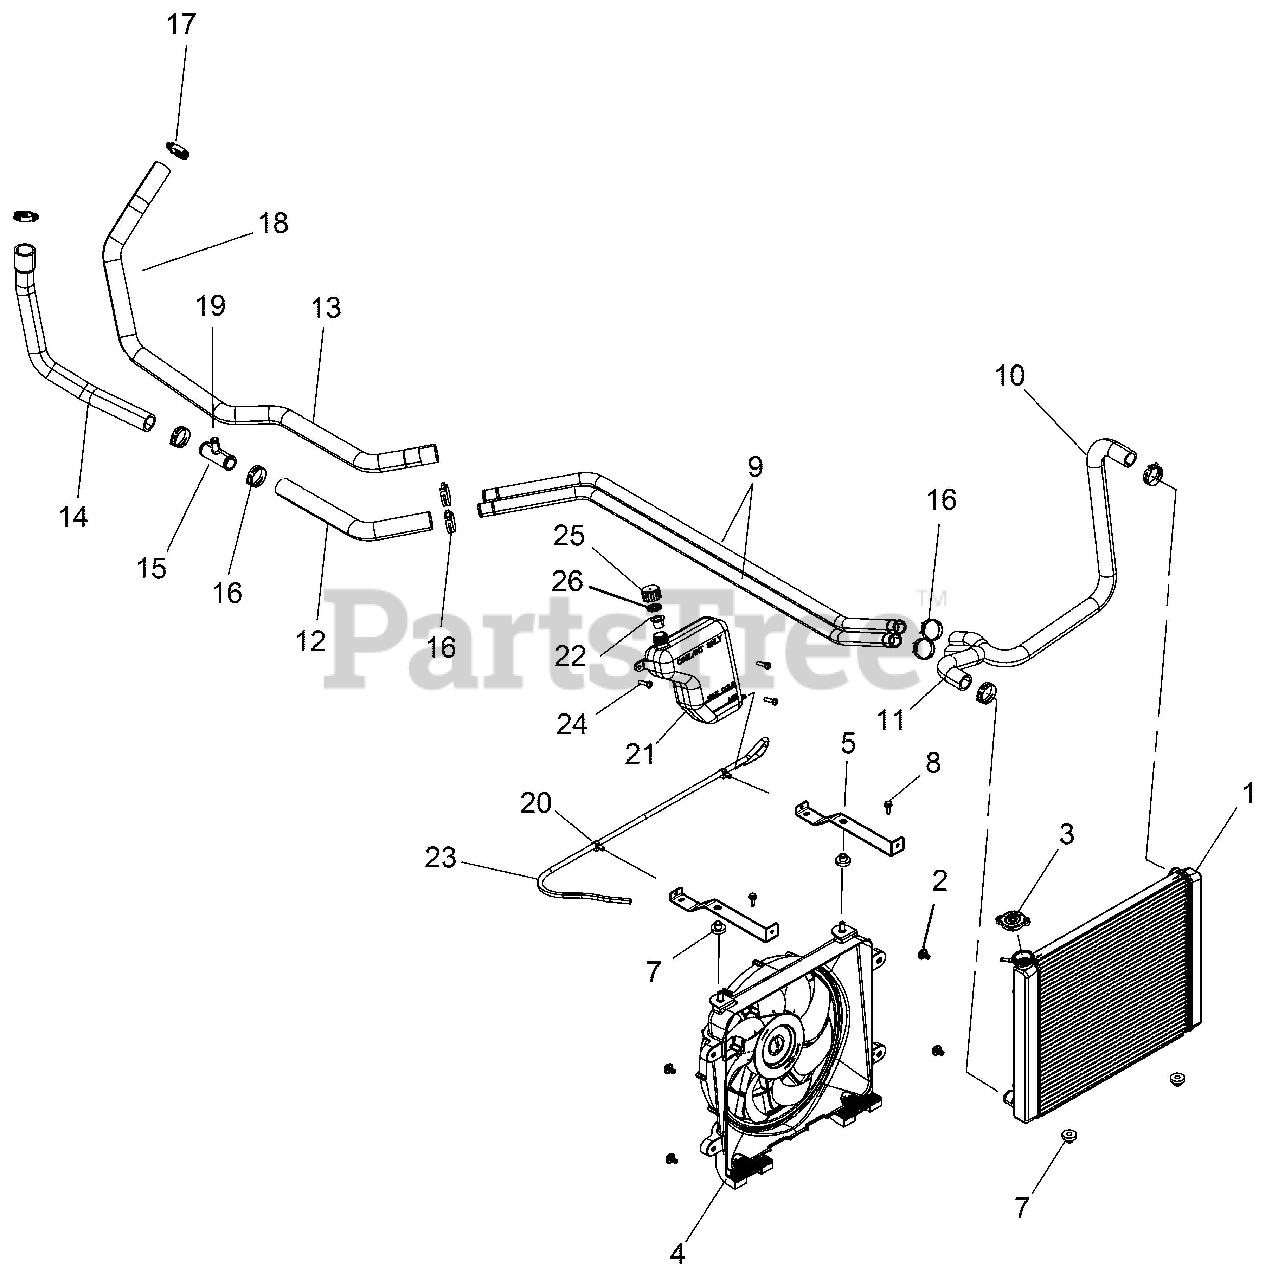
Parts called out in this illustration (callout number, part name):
1	ASM-RADIATOR, CORE
2	BOLT-M6X15MM
4	FAN-ASSEMBLY
5	MOUNT, RADIATOR, BLACK
8	SCR-M6 X 1.0 X 20, HXHD, FLG, TDFM, BL
9	TUBE-COOLANT, 1"
10	HOSE-UPPER, RAD
11	HOSE-LOWER, RAD
12	HOSE, ENGINE, IN
13	HOSE, ENGINE, OUT
14	HOSE, ENGINE, BYPASS
15	CONNECTOR-TEE, 1 X 1 X 0.5
16	CLAMP, SPRINGBAND 35/12, BLK
17	CLAMP-HOSE(WORM DR) 25-40MM
18	CLIP-ROUTING
19	CLAMP-HOSE, SPRING, 20MM
21	TANK-SURGE
22	CAP, PLUG 9X(GRN), FLEX TEMP (10)
23	FUEL LINE-95 CENTIMETERS
24	SCR-#14 X 1 HI/LO-PH-PN-TRX-M
25	CAP, OVERFLOW
